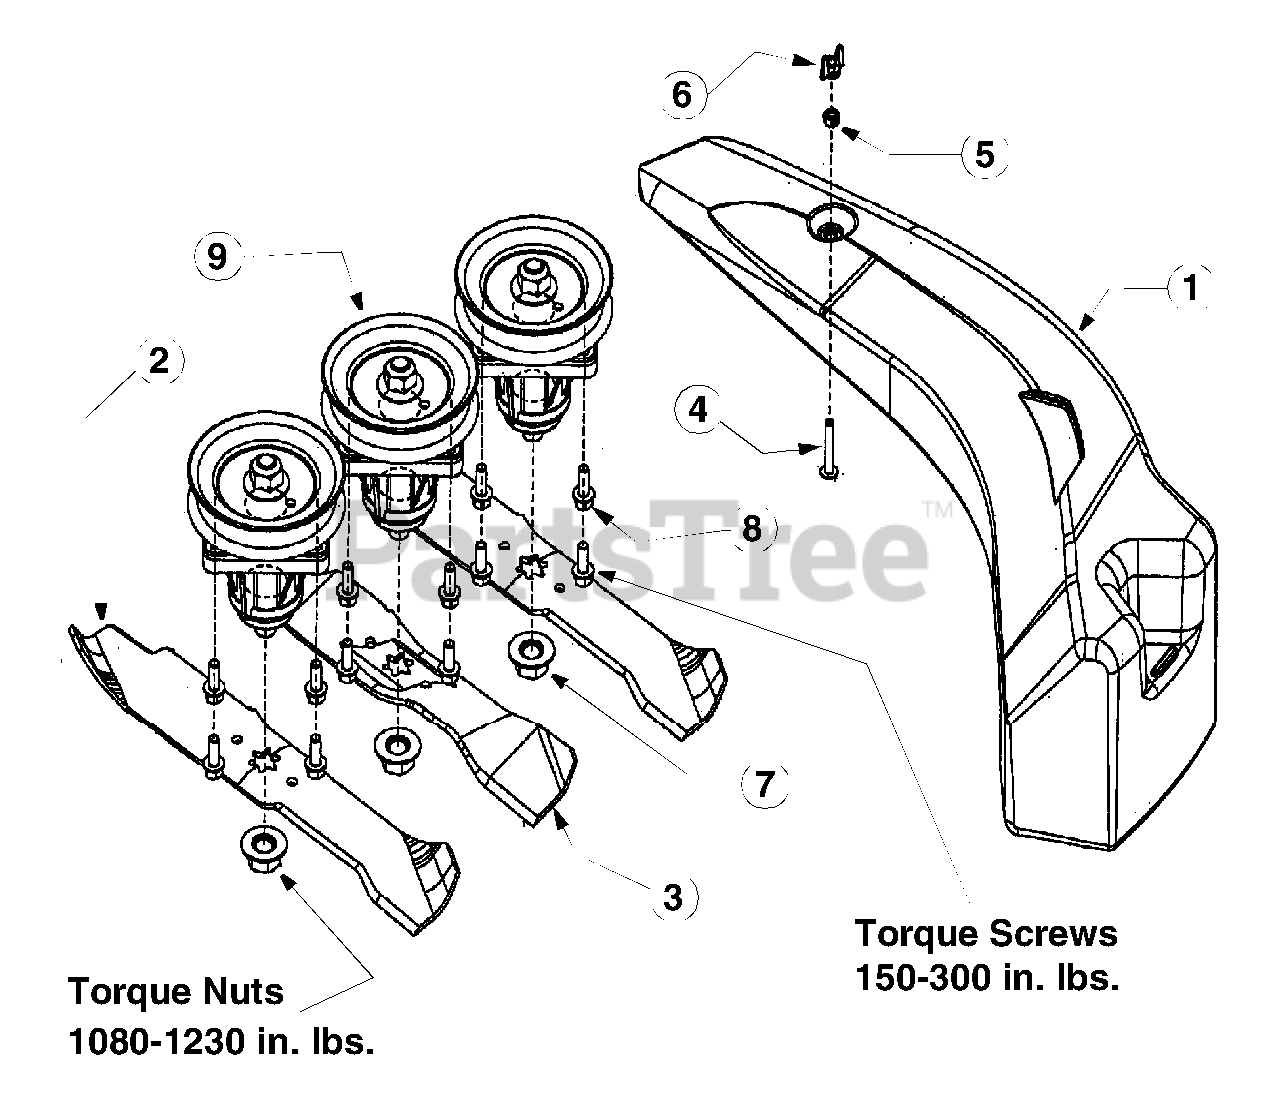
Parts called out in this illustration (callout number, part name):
1	Mulching Plug
2	16.28" 3 in 1 Blade
3	14.88" 3 in 1 Blade
4	Machine Screw (1/4")
5	Hex Locking Nut (1/4")
6	Wing Nut (1/4")
7	Hex Nut (5/8" Flange)
8	Screw (1/4")
9	Spindle Assembly
